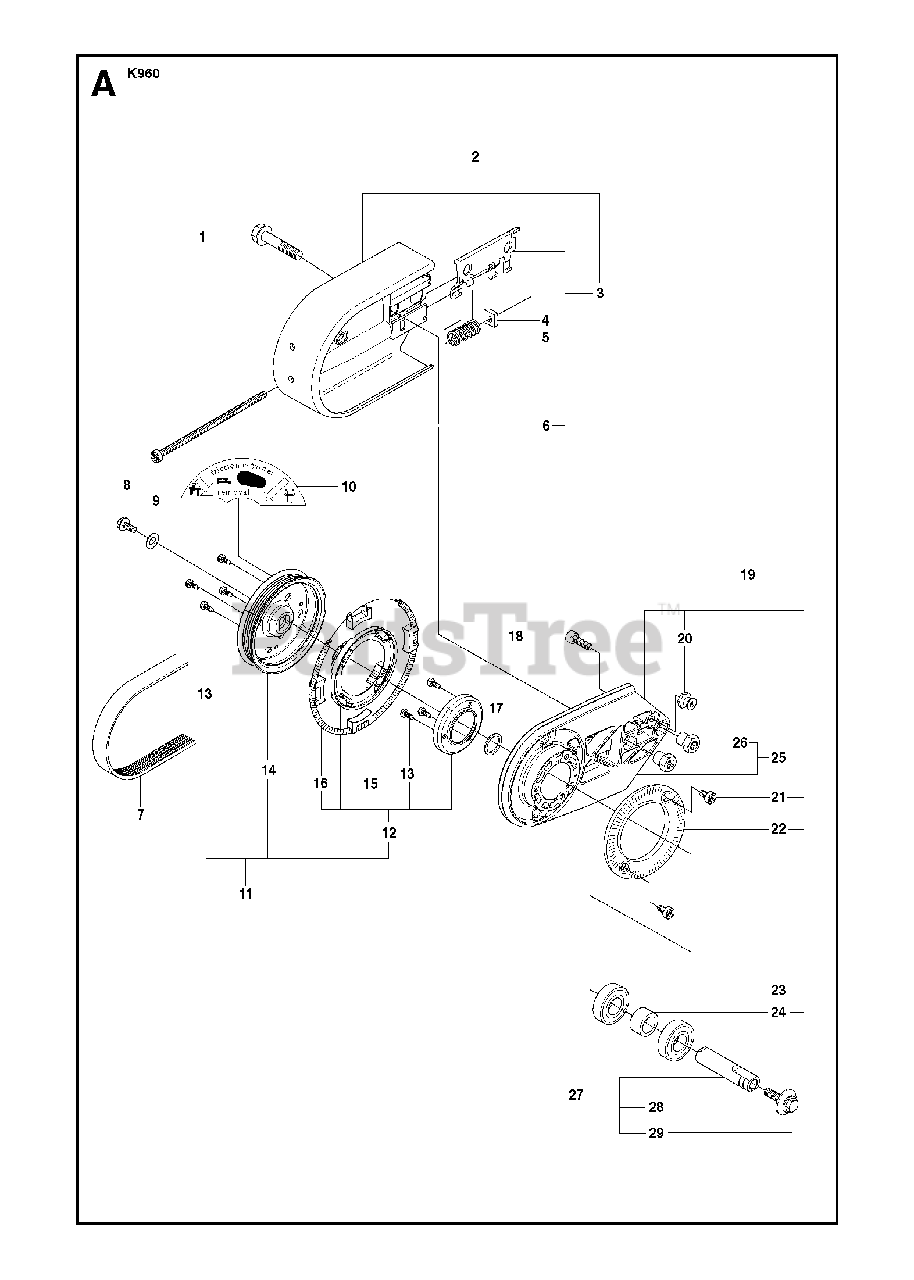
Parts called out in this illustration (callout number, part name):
2	BELT GUARDIncl. 3
3	BELT TENSIONER ASSYIncl. 4, 5, 6
5	COMPRESSION SPRING
6	SCREW CITXSCM
7	BELT"12"", 14"""
11	PULLEYIncl. 12 - 16
12	PULLEYIncl. 13, 15, 16
13	SCREW CCRPANT
14	PULLEY
19	BEARING HOUSINGIncl. 20 - 24
20	TORSION STOP
21	SCREW ITXSCM
23	BALL BEARING
25	BEARING HOUSINGIncl. 26
27	SHAFTIncl. 28, 29
